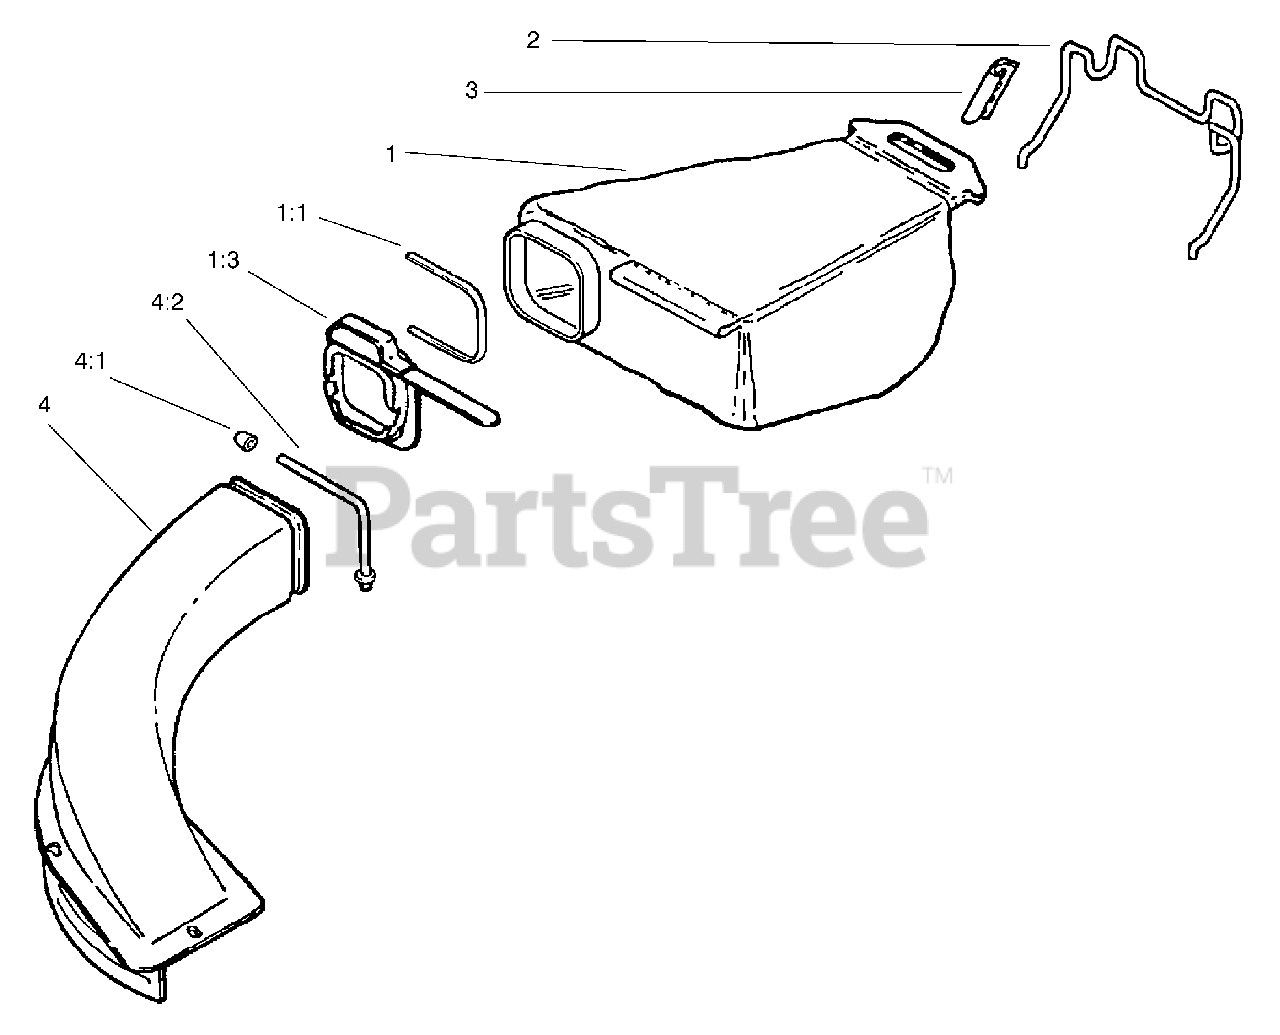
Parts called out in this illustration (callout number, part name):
1	Bag & Adapter ASM
1:1	Tie Strap
2	Wire Hanger,
3	Clamp-Hanger
4	Chute & Support
4:1	Nut-Cap
4:2	Support-Chute
